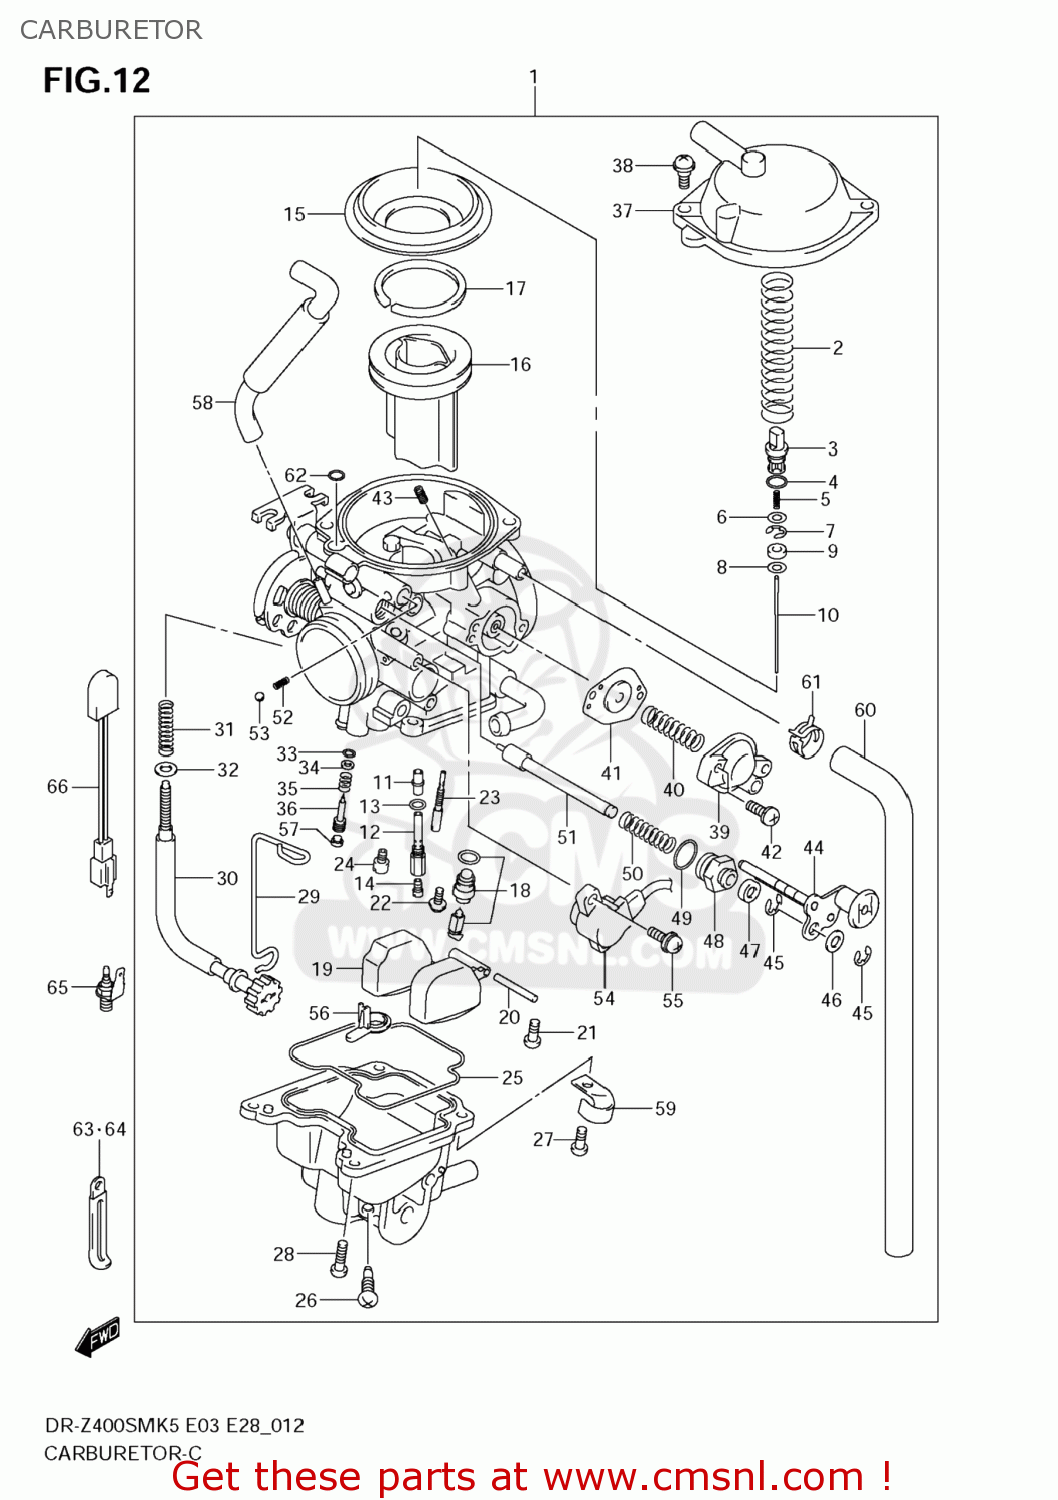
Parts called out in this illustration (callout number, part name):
1	CARBURETOR ASSY
2	SPRING
3	HOLDER
4	O RING(D:1.9,ID:4.8)
5	SPRING
6	WASHER
7	E RING,MULTIPLE JET NOZZLE
8	RING
9	WASHER
10	NEEDLE,JET
11	JET
12	HOLDER,JET
13	O RING
14	JET,MAIN(142.5)
15	DIAPHRAGM
16	VALVE,PISTON
17	RING
18	VALVE ASSY,NEEDLE
19	FLOAT ASSY
20	PIN,FLOAT
21	SCREW
22	SCREW
23	JET,PILOT(22.5)
24	JET,MAIN(62.5)
25	GASKET (NAS)
26	SCREW,DRAIN
27	SCREW
28	SCREW
29	CLIP
30	SCREW,ADJUST
31	SPRING,THROTTLE SCREW
32	WASHER,STARTER SHAFT
33	O RING,PILOT AIR SCREW
34	WASHER
35	SPRING,THROTTLE SCREW
36	ADJUSTER
37	COVER ASSY,DIAPHRAGM
38	SCREW
39	COVER ASSY
40	SPRING
41	DIAPHRAGM ASSY
42	SCREW
43	JET,POWER(135)
44	PLATE ASSY
45	E RING
46	WASHER
47	CAP,STARTER VALVE
48	GUIDE SCREW,PLUNGER
49	O RING
50	SPRING
51	PLUNGER ASSY
52	SPRING
53	BALL,CARBURETOR
54	SENSOR ASSY
55	SCREW
56	RING
57	PLUG
58	HOSE
59	PLATE
60	HOSE,AIR VENT(6.5X10.5)
61	CLIP
62	O RING
63	CLAMP(L:65)
64	CLAMP(L:120 T:1.0)
65	HEATER ASSY,CARBURETOR(15W)
66	THERMO SWITCH,CARB HEATER
